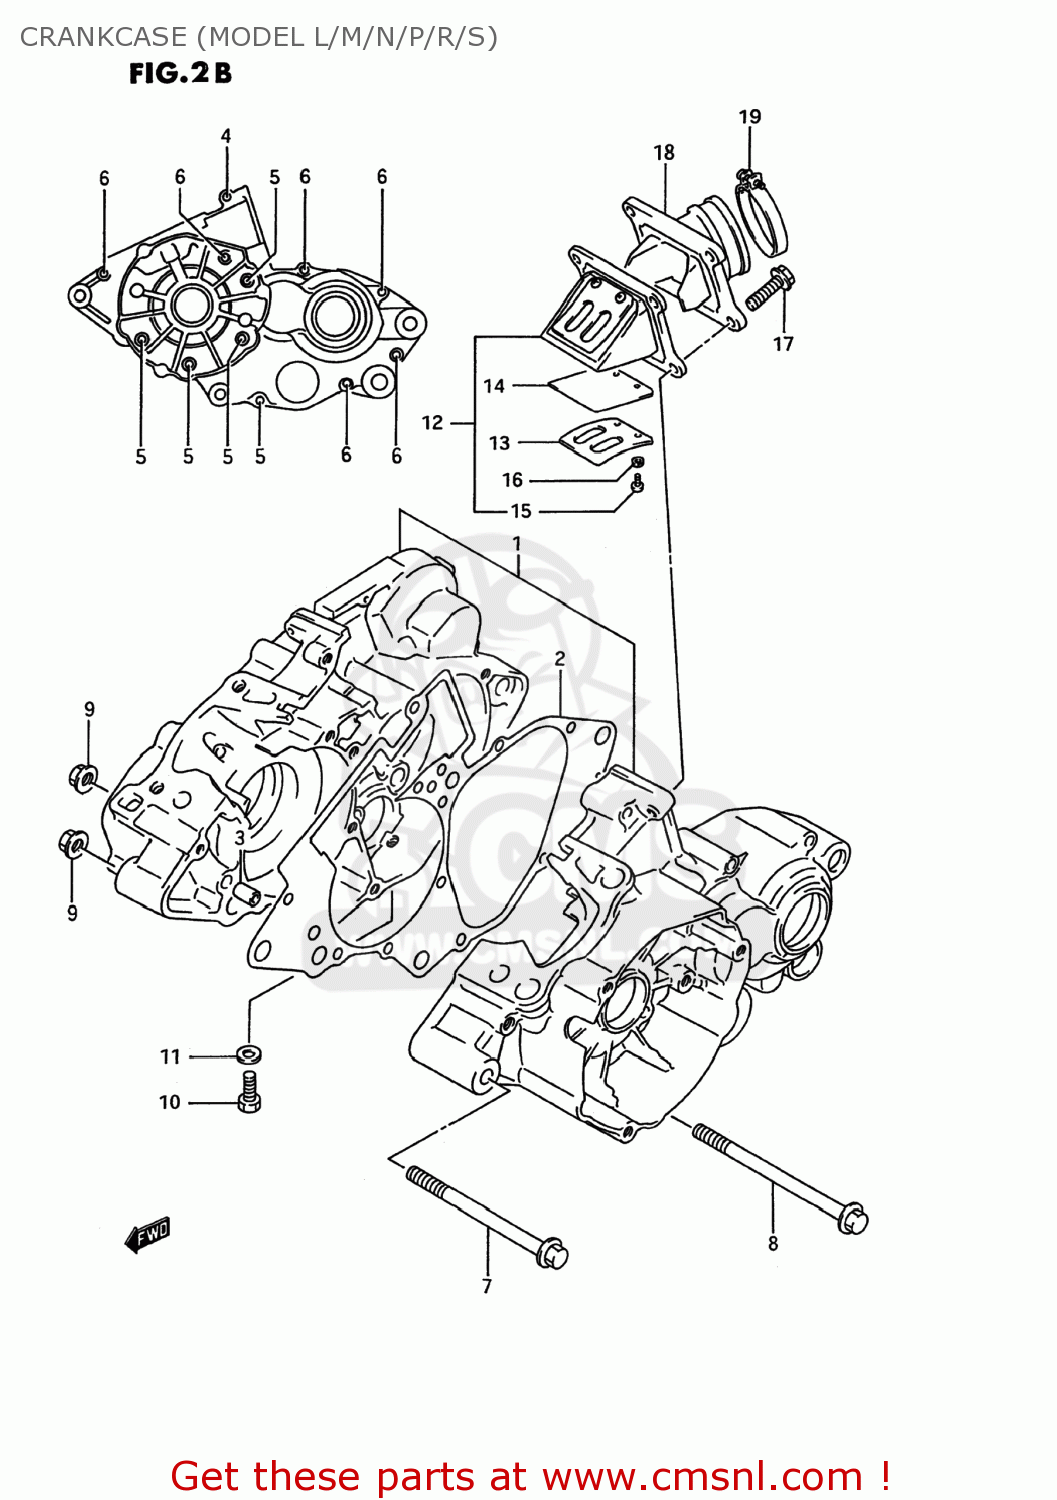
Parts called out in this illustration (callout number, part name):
1	CRANKCASE SET
2	GASKET,CRANKCASE (NAS)
3	PIN
4	BOLT
5	BOLT
6	BOLT
7	BOLT
8	BOLT
9	NUT
10	BOLT
11	GASKET (NAS)
12	VALVE ASSY,REED
13	STOPPER,REED VALVE
14	VALVE,REED
15	SCREW
16	WASHER,LOCK
17	BOLT
18	PIPE,INTAKE
19	CLAMP
